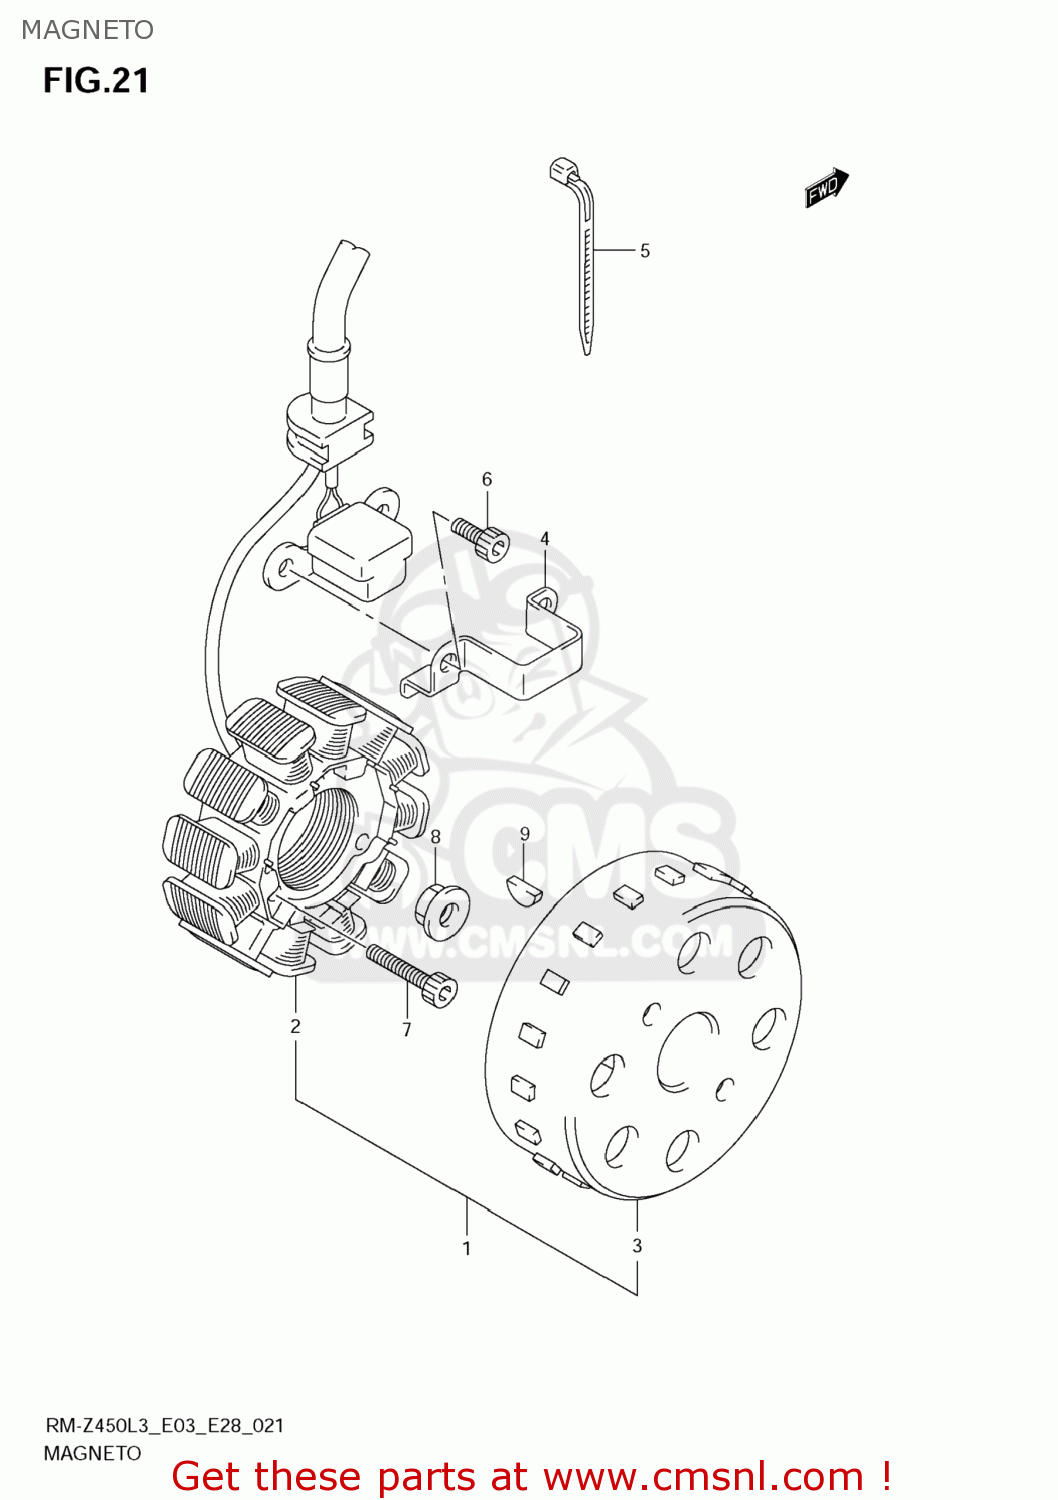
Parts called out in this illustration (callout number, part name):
1	MAGNETO ASSY
2	STARTER ASSY
3	ROTOR ASSY
4	CLAMP,MAGNETO LEAD
5	CLAMP(L:165)
6	BOLT
7	BOLT
8	NUT
9	KEY
